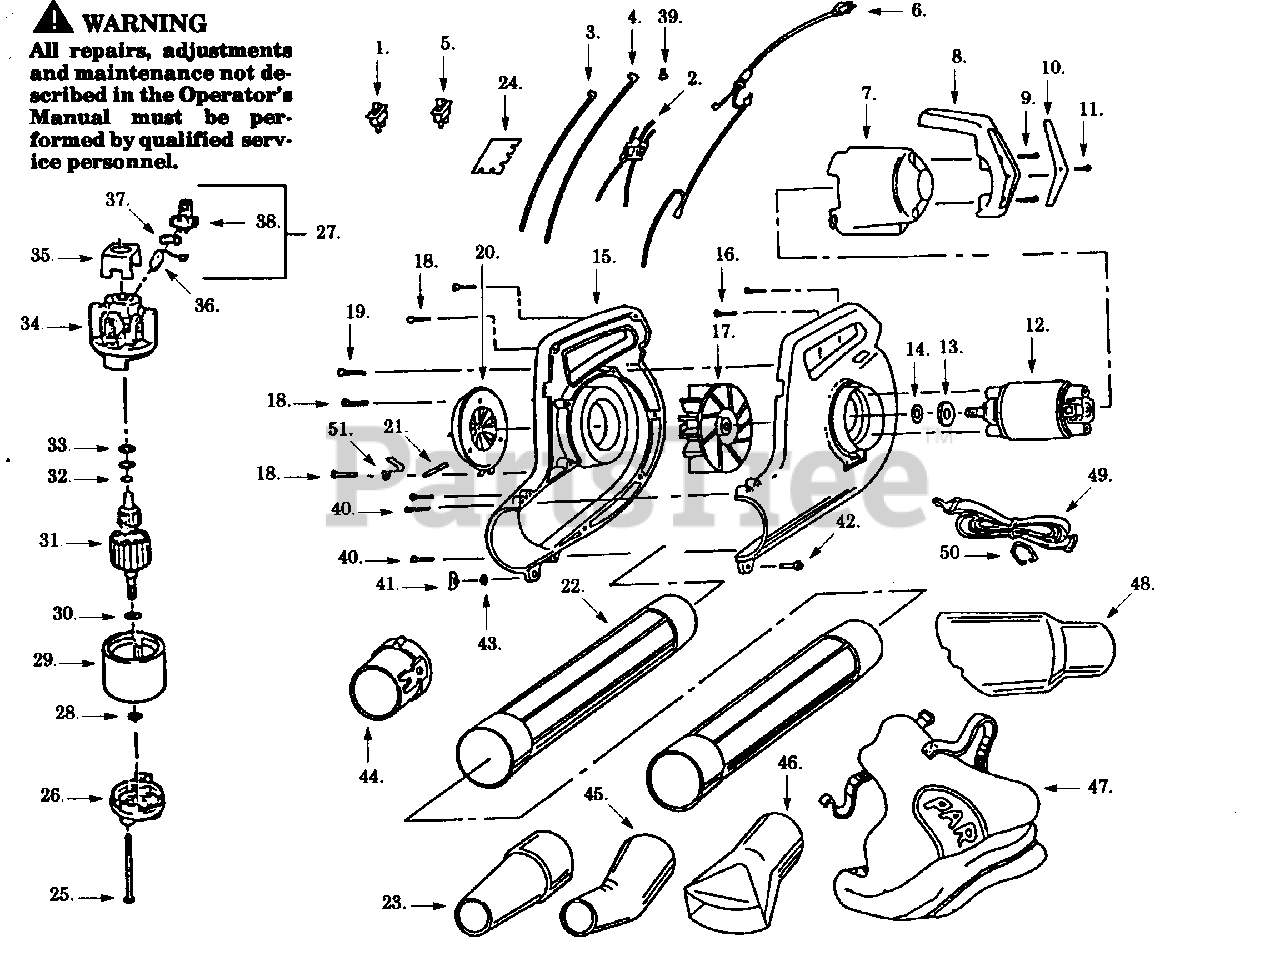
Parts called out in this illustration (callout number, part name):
1	On-Off Switch
2	P.C. Board Ass'y.
3	Lead Wire Ass'y.
4	Lead Wire Ass'y.
5	Speed Switch
6	Power Cord Ass'y.
7	Motor Cover
14	Retainer Ring
15	R.H./L.H. Housing
17	Impeller Ass'y.
20	Inlet Cover
21	Hinge Pin
22	Outlet Tube
24	Mounting Board
26	Endbell Output
27	Brush Kit (Incl. 36,37,38)
29	Field Ass'y.
30	Retainer Ring
31	Armature
32	Retainer Ring
34	Endbell (Brush)
35	Insulator
37	Brush Spring
38	Brush Holder
39	Connector
41	Wing Nut
44	Adapter Tube Ass'y.
45	Curved Nozzle
46	Diffuser Ass'y.
47	Vacuum Bag
48	Vacuum Nozzle Ass'y.
49	Shoulder Strap
